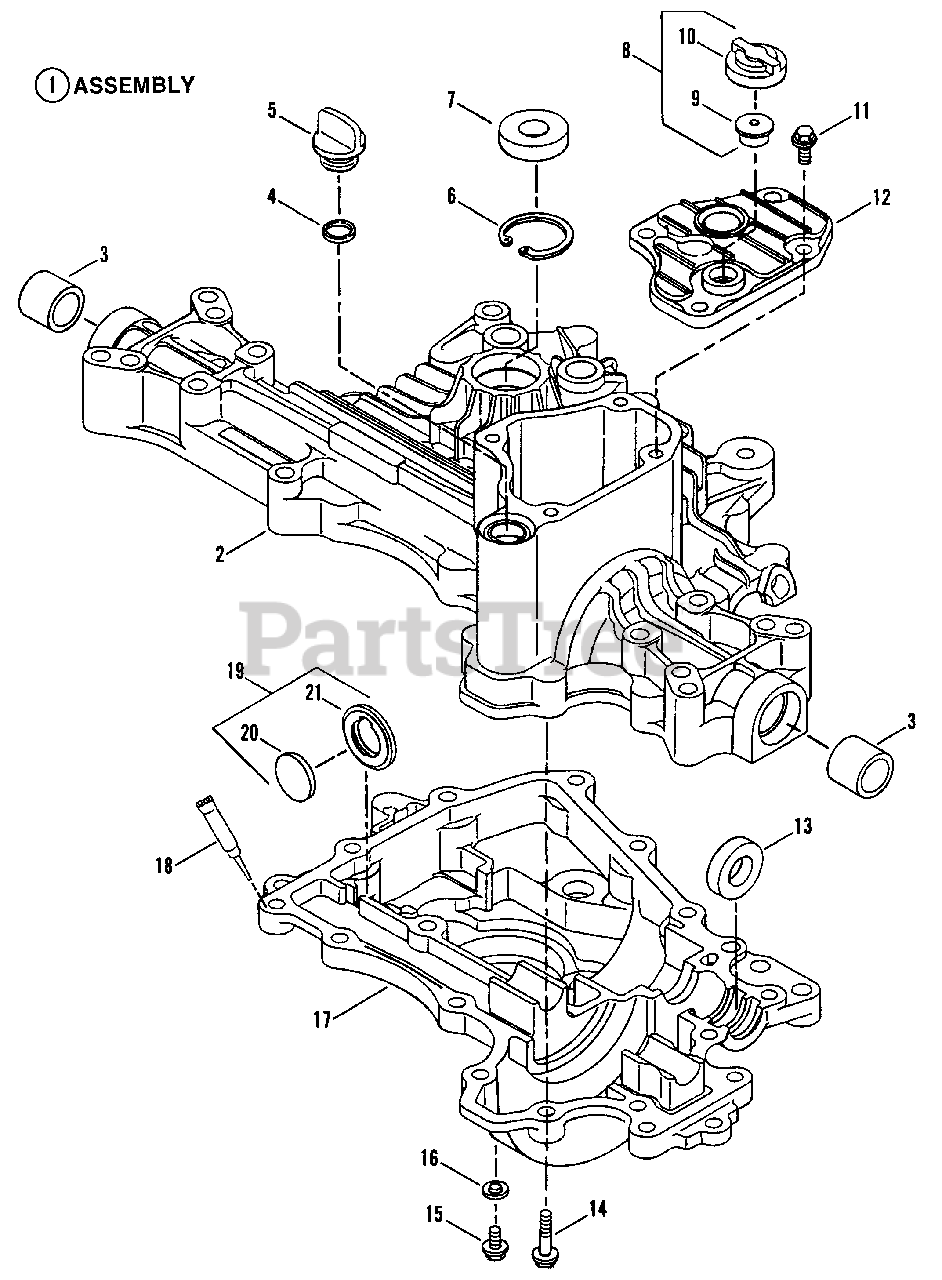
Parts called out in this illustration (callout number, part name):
1	ASSEMBLY, Upper Case Housing (K50)
3	BUSHING, Axle Shaft
5	CAP, Oil Fill
6	SNAP-RING
7	SEAL, Input Shaft
8	ASSEMBLY, Vent Valve
9	BODY, Vent Valve
10	CAP, Vent Valve
11	CAPSCREW, M8x20mm
12	COVER, Oil Reservoir
13	SEAL, Output Shaft
14	CAPSCREW, M8x30mm Self-Tapping
15	PLUG, Drain
16	WASHER, Seal
17	HOUSING, Lower Case (K50)
18	SEALANT, Silicone
19	ASSEMBLY, Magnet
20	MAGNET
21	SEAL, Magnet
